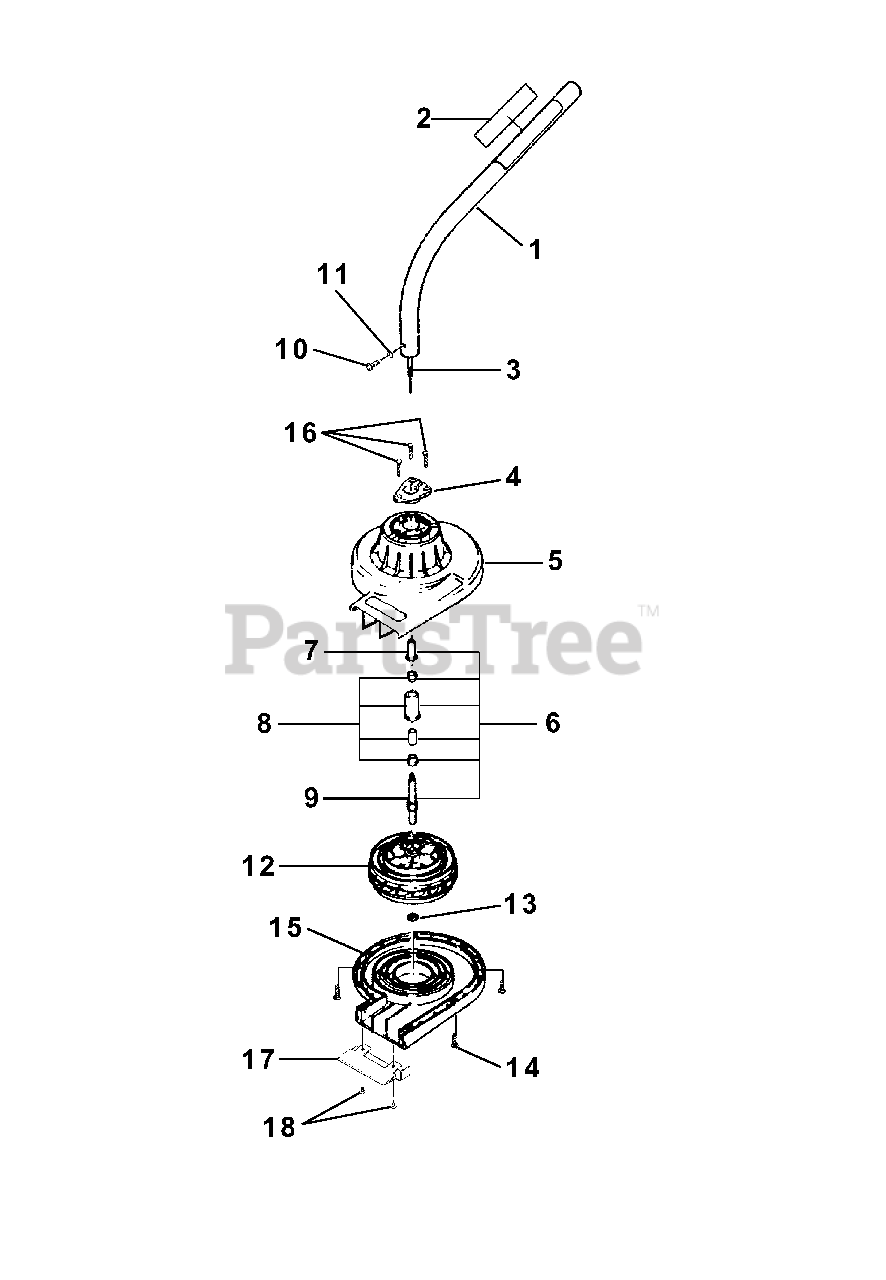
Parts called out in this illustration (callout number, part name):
1	DRIVESHAFT HOUSING
2	DECAL-Warning
3	CABLE-Flex
5	UPPER HOUSING
6	BEARING HOUSING
7	ADAPTER-Arbor
8	BUSING
9	SHAFT-Arbor
10	SCREW (10-24 x .312")
11	WASHER, Lock (#10)
12	IMPELLER
13	CLIP
14	SCREW, Pan Hd. (8-16 x .750)
15	LOWER HOUSING
16	SCREW-Thread Forming (8-16 x 1")
17	GUARD-Lower Housing
18	SCREW (10-16 x 1/4")
